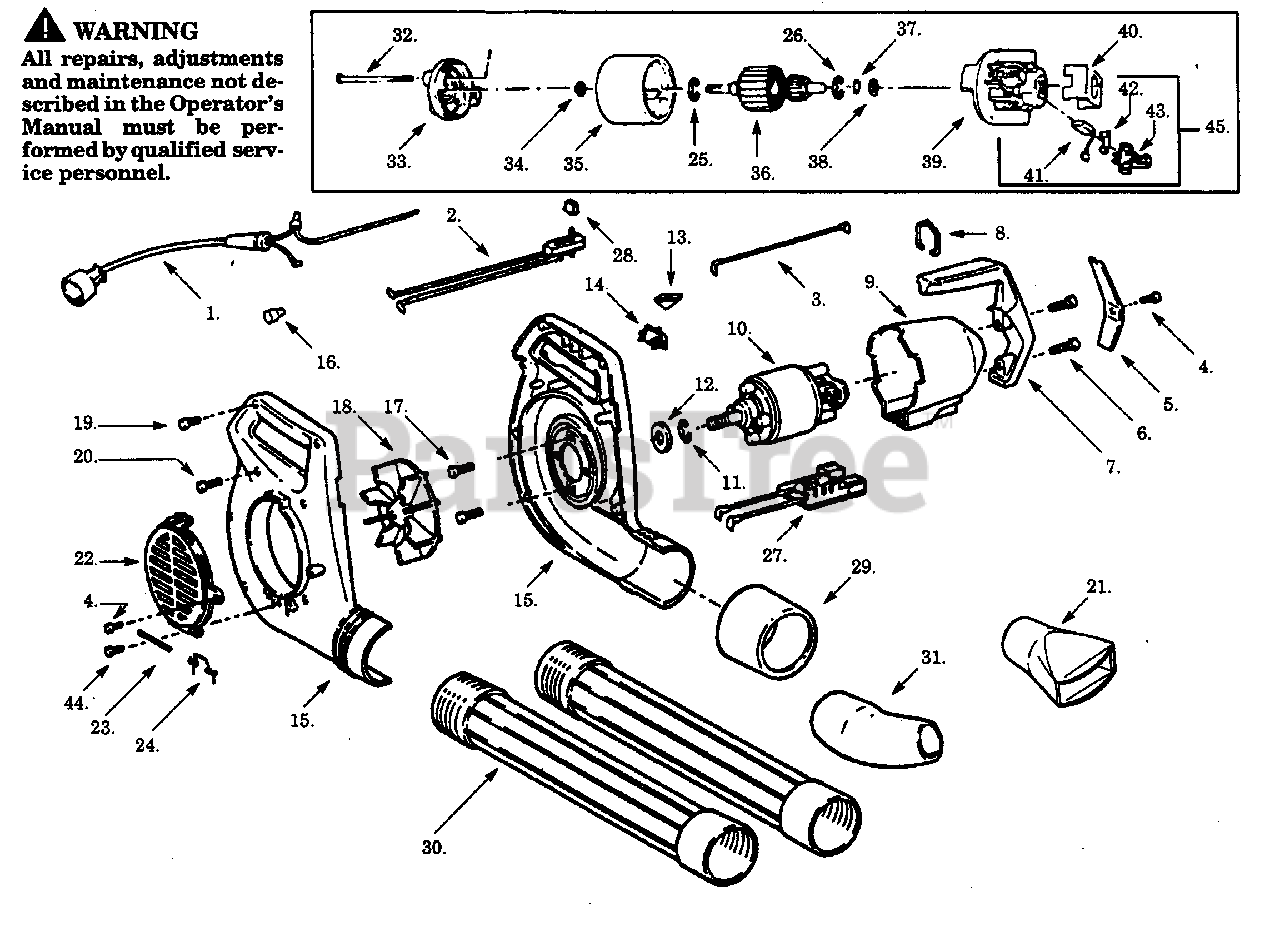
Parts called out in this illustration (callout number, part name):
1	Power Cord Ass'y.
2	Speed Switch Ass'y.
3	Leadwire Ass'y.
7	Side Handle
9	Motor Cover
10	Motor Ass'y.
11	Retaining Ring
13	Switch Cover
14	On/Off Switch
15	Housing Set
16	Terminal Connector
18	Impeller Ass'y.
21	Nozzle Diffuser
22	Inlet Cover
23	Pin Hinge
24	Return Spring
25	Retaining Ring
26	Retaining Ring
27	P.C. Board Ass'y.
29	Ferrule Sleeve
30	Outlet Tube
33	Endbell Ass'y. (Drive)
35	Field Ass'y.
36	Armature Ass'y.
39	Endbell Ass'y. (Brush)
40	Insulator
42	Brush Spring
43	Brush Holder
45	Brush Kit (Incl. 41,42,43)
